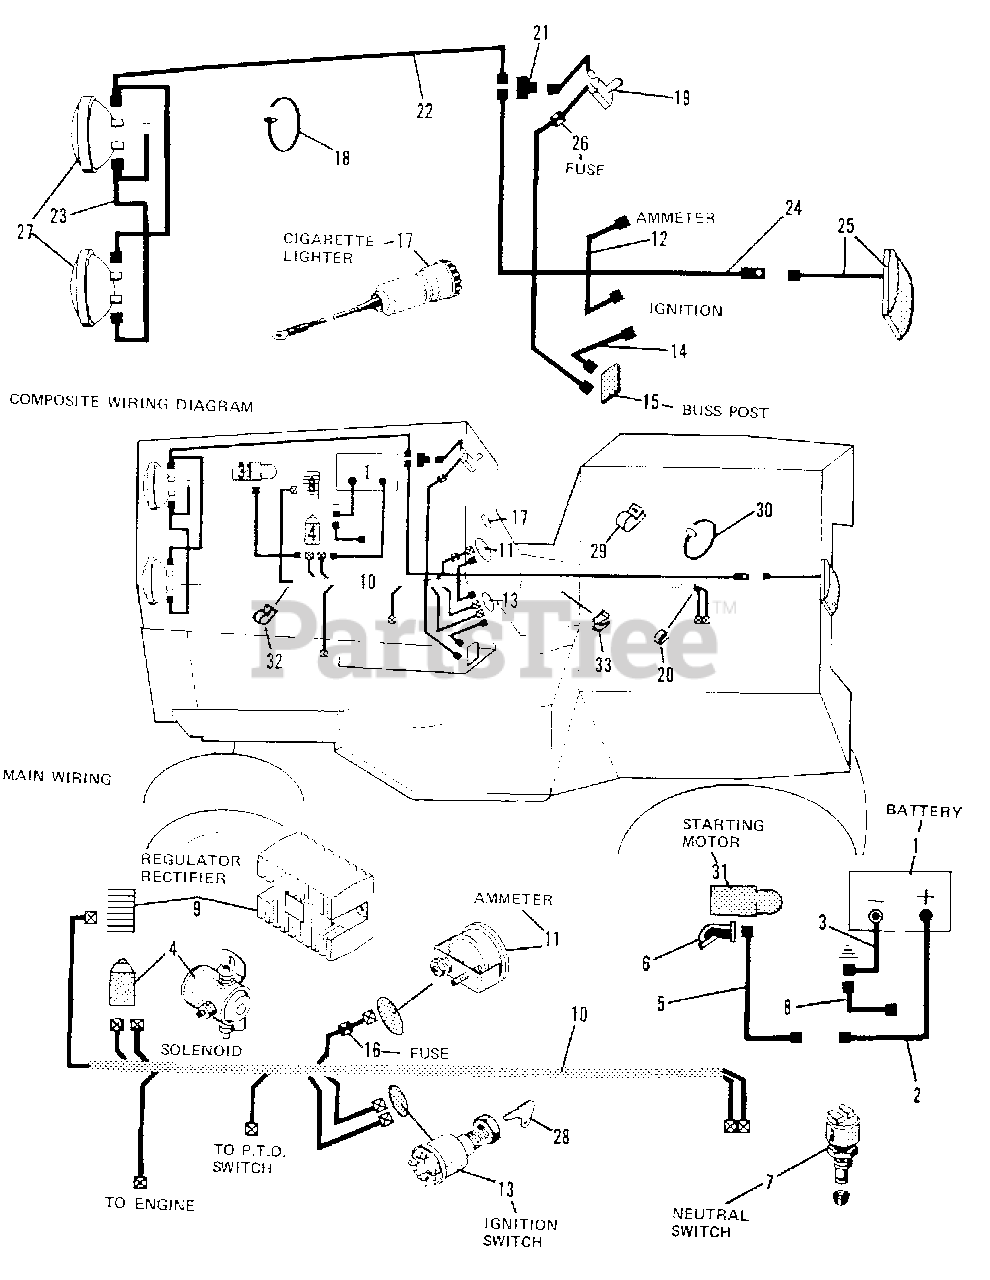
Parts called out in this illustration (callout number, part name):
1	BATTERY, 12 Volt - 45 amp./Hour
2	CABLE, Battery, (To Solenoid)
3	CABLE, Battery, (To Ground)
4	SOLENOID, Starter (2-3/4" Large Mounting Strap f/Magneto Ingnition)
4	SOLENOID, Starter (3-1/4" Large Mounting Strap f/Breaker Point Ingnition)
4	CAPSCREW, 1/4NC x 3/4
4	WASHER, 9/32 x 5/8 x 1/16
4	LOCKWASHER, #10
4	NUT, #10NF
5	CABLE, Solenoid To Starter
6	COVER, Rubber Terminal
7	SWITCH, Momentary
7	NUT, Special Hexagon
7	BOOT, Rubber
8	CABLE, Solenoid To Ground
9	REGULATOR, Rectifier (15 amp)
9	BOLT, 1/4NC x 1, Carriage
10	HARNESS ASSEMBLY, Wiring (For Magneto Ingnition System)
10	HARNESS ASSEMBLY, Wiring (For Breaker Point Ignition System)
11	AMMETER (45-0-45)
12	LEAD, Ammeter to Switch (Used Only On Magneto Ignition System For Breaker Point Wiring-See Item 20)
13	SWITCH, Ignition (4 Terminals - For Magneto Ignition System)
13	SWITCH, Ignition (5 Terminals - For Breaker Point Ignition System)
13	NUT, Face
13	LOCKWASHER, Internal Tooth
14	LEAD, Buss Post To Switch, Used Only On Magneto Ignition System - For Breaker Point Wiring - See Item 20)
15	STRIP, Buss Post Insulator
15	WASHER, Insulator
15	Lockwasher, 1/4
15	WASHER, 9/32 x 5/8 x 1/16
15	NUT, 1/4NC
15	SCREW, #10NC x 1-1/4, Round Head, Machine
15	WASHER, #10 S.A.E.
15	LOCKWASHER, #10
15	NUT, #10NC
16	FUSE, 30 AMP (For Magneto Ignition)
16	BREAKER, Circuit (For Breaker Point Ignition)
17	LIGHTER, Cigarette
17	PLUG (For Models Without Lighter)
18	TIE, Cable (Used as Required)
19	SWITCH, Light
19	PLUG (For Models Without Lighter)
20	CLIP, Cable (Hydrostatic Only)
21	CONNECTOR, Insulated
22	HARNESS ASSEMBLY, Front Headlight
23	HARNESS ASSEMBLY, Gound
24	LEAD, Taillight
25	LAMP ASSEMBLY, Rear (Complete)
25	LENS, Red
25	NUT, #8NC
25	SCREW, #8NC x 1/2
25	LOCKWASHER, #8
26	FUSE, 14 amp
27	LAMP, Sealed Beam
28	KEY, Ignition Switch (Used On Magneto Ignition 4 Terminal Switch)
28	KEY, Ignition Switch (Used On Breaker Point Ignition 5 Terminal Switch)
29	CLIP, Closed (Mounts On Firewall)
30	TIE, Cable (Used Where Required)
31	STARTER (Refer to ENGINE ELECTRICAL SYSTEM)
32	CLIP, Cable
33	CLIP, Speed
